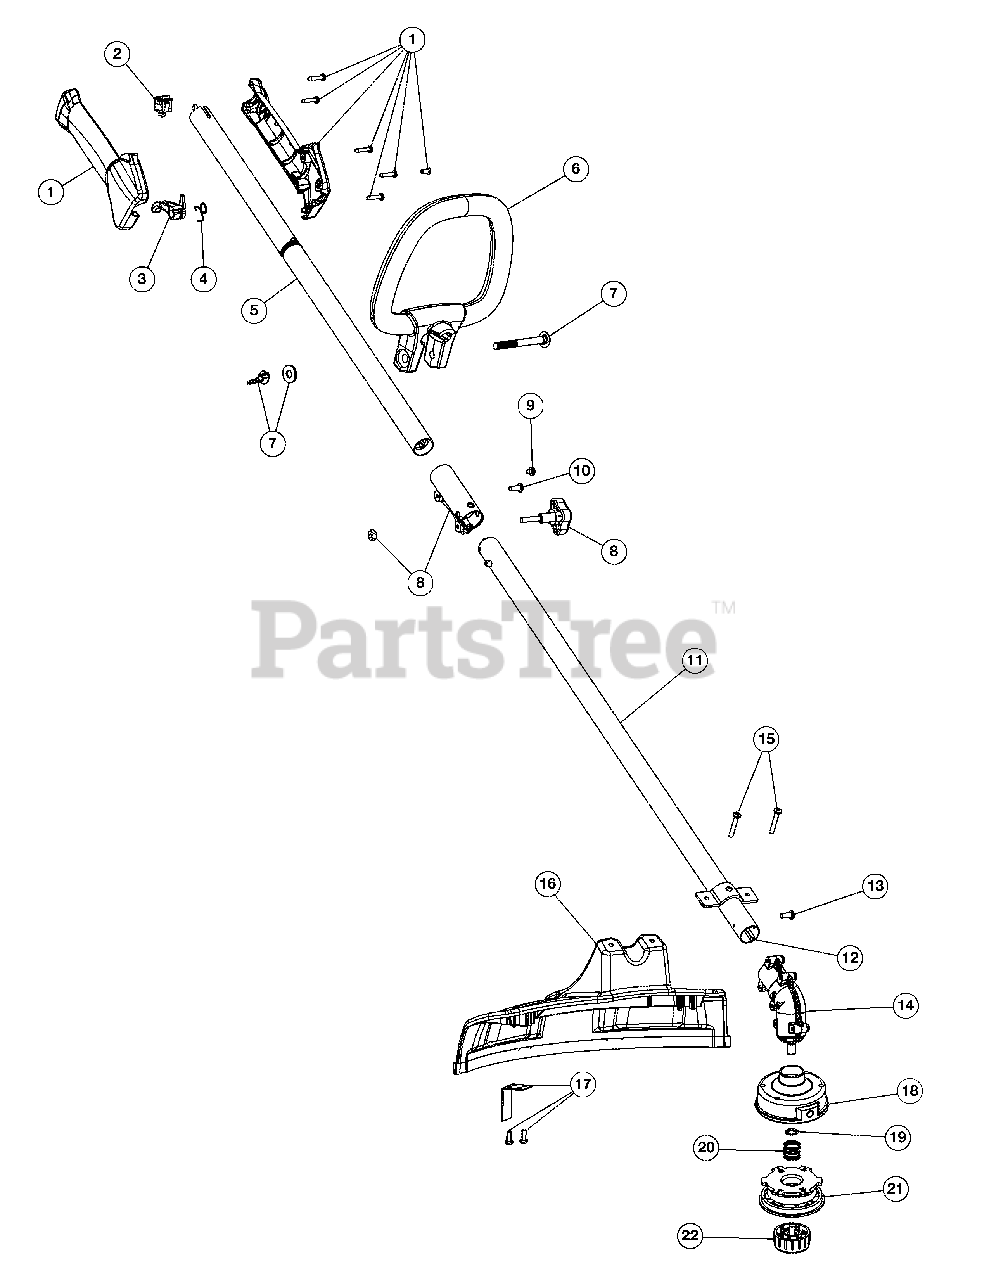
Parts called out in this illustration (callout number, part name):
1	Throttle Housing Assembly (Incl. 2-4)
2	Throttle Trigger
3	Throttle Trigger Spring
5	Upper Drive Shaft Housing Assembly
6	D-Handle (Incl. 7)
7	D-Handle Hardware Assembly
8	Split Boom Coupler (Incl. 9-10)
11	Lower Drive Shaft Housing Assembly (Incl. 12)
12	Lower Flexible Drive Shaft
13	Anti-Rotation Screw
14	Gear Box Assembly (Incl. 13 & 18-22)
15	Shield Mounting Screws
16	Shield Assembly (Incl. 15 & 17)
17	Blade Assembly
18	Outer Spool Assembly
19	Retainer
21	Inner Reel
22	Bump Knob Assembly
